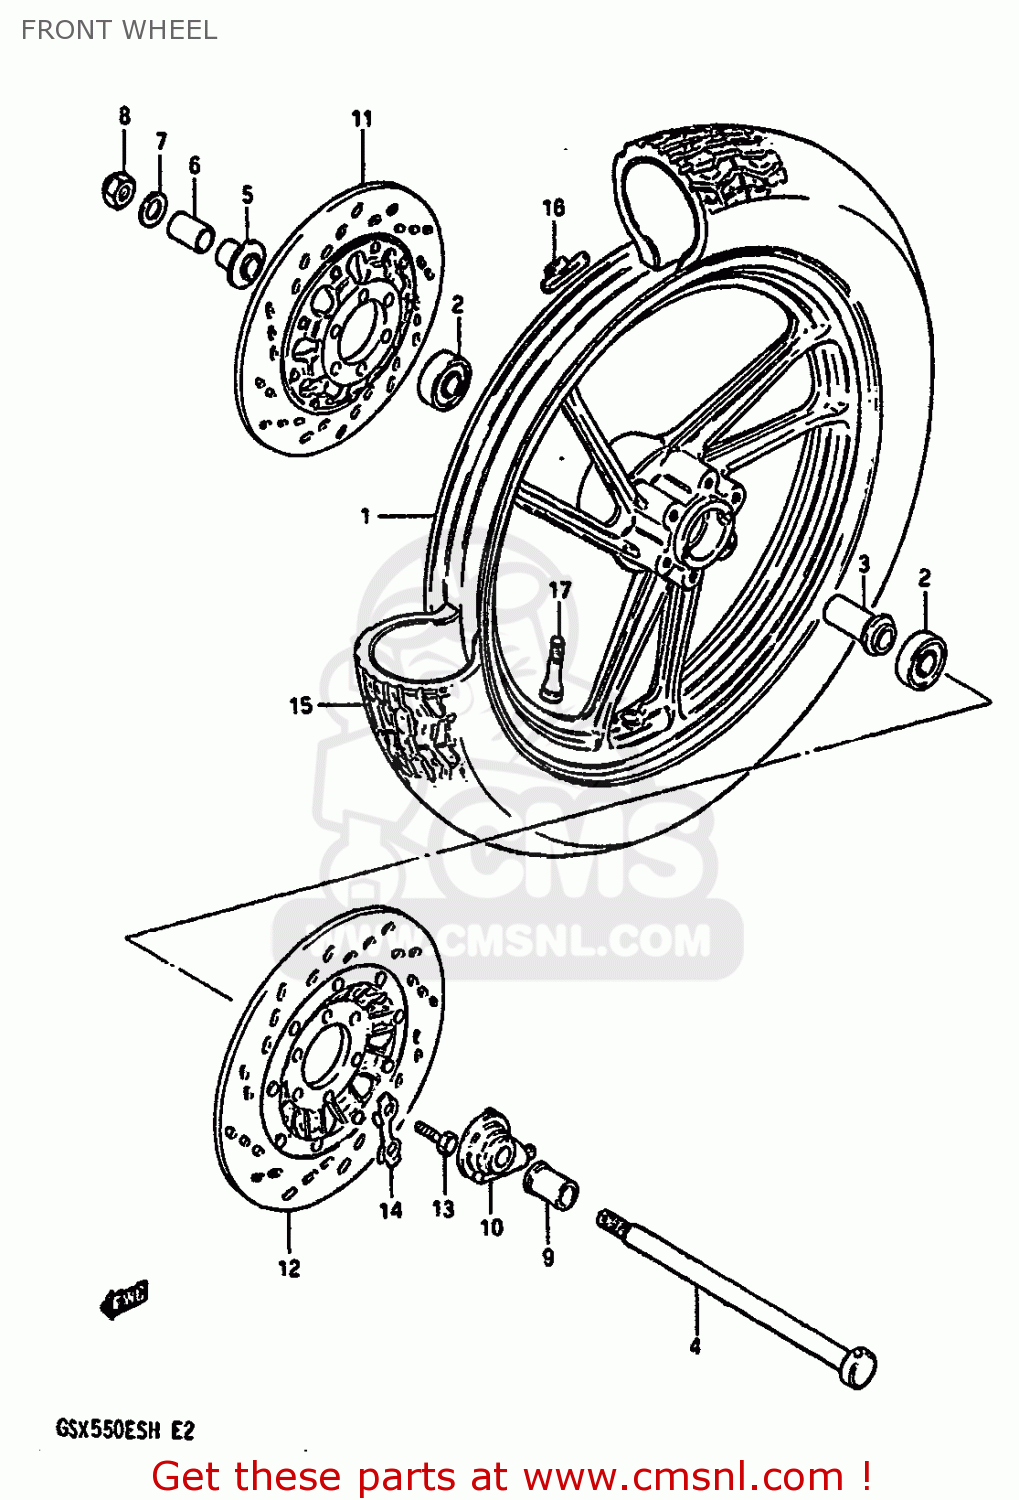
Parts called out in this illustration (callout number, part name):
1	WHEEL,FRONT
2	BEARING
3	SPACER,FR HUB BEARING
4	AXLE,FR
5	SPACER,FR AXLE,R
6	SPACER,FR AXLE,R
7	WASHER
8	NUT
9	SPACER,FR AXLE,L
10	BOX ASSY,SPEEDOMETER GEAR
11	DISC,BRAKE,RIGHT
12	DISC,BRAKE,LEFT
13	BOLT(8X30)
14	WASHER
15	TIRE,FRONT
16	BALANCER,WHEEL
17	VALVE,TIRE
